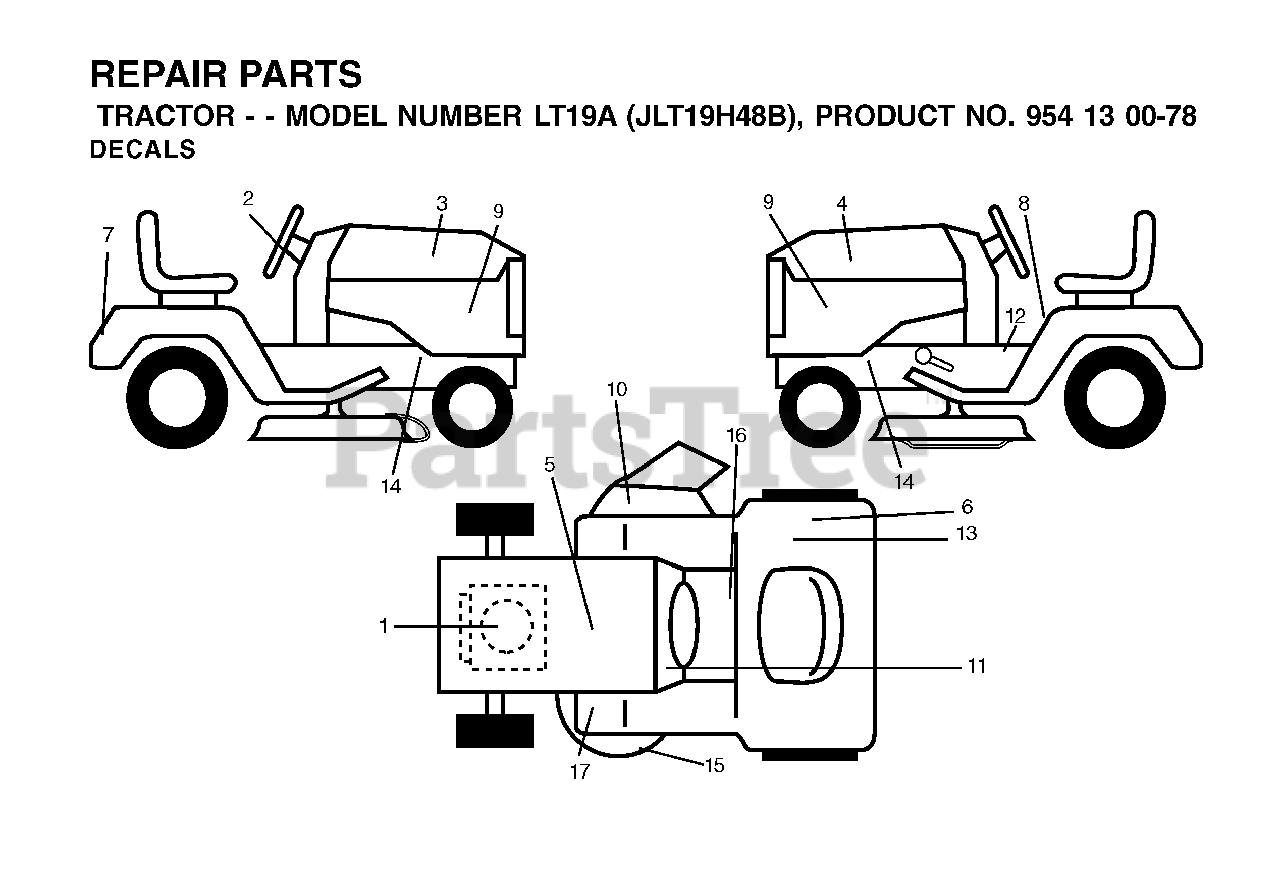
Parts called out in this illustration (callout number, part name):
5	DECAL BTRY SYMBOLS
6	DECAL.FENDER
8	DECAL READ OWNER'S MAN SYMS
10	DECAL MOWER CUT/FINGER
12	DECAL PARK BRAKE
13	DECAL EUROPE STANDARD CE
15	DECAL V-BELT SCHEMATIC
